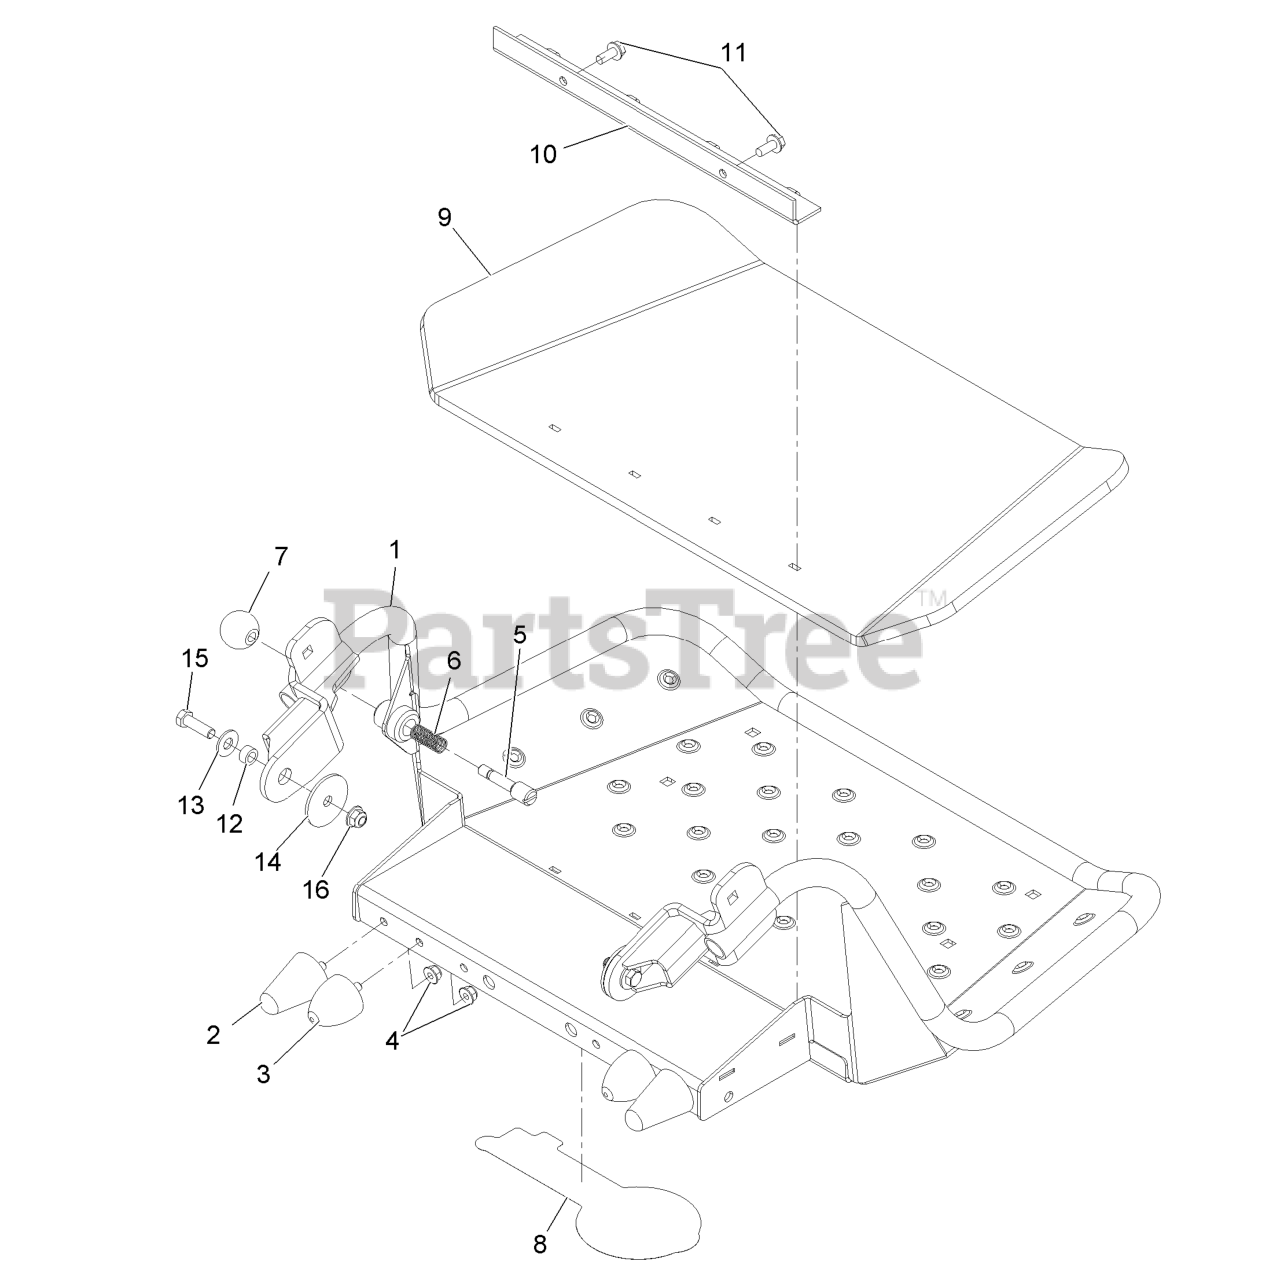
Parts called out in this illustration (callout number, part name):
2	BUMPER-RUBBER
3	BUMPER-RUBBER
4	NUT-HF, NI
5	PIN-LATCH
7	KNOB-BALL
8	DECAL, EXMARK LOGO
10	CLAMP-SHIELD
11	SCREW-THD ROLL, HWH
12	SPACER
13	WASHER-FLAT
14	WASHER-FLAT
15	SCREW-HH
16	NUT-HF, NI
